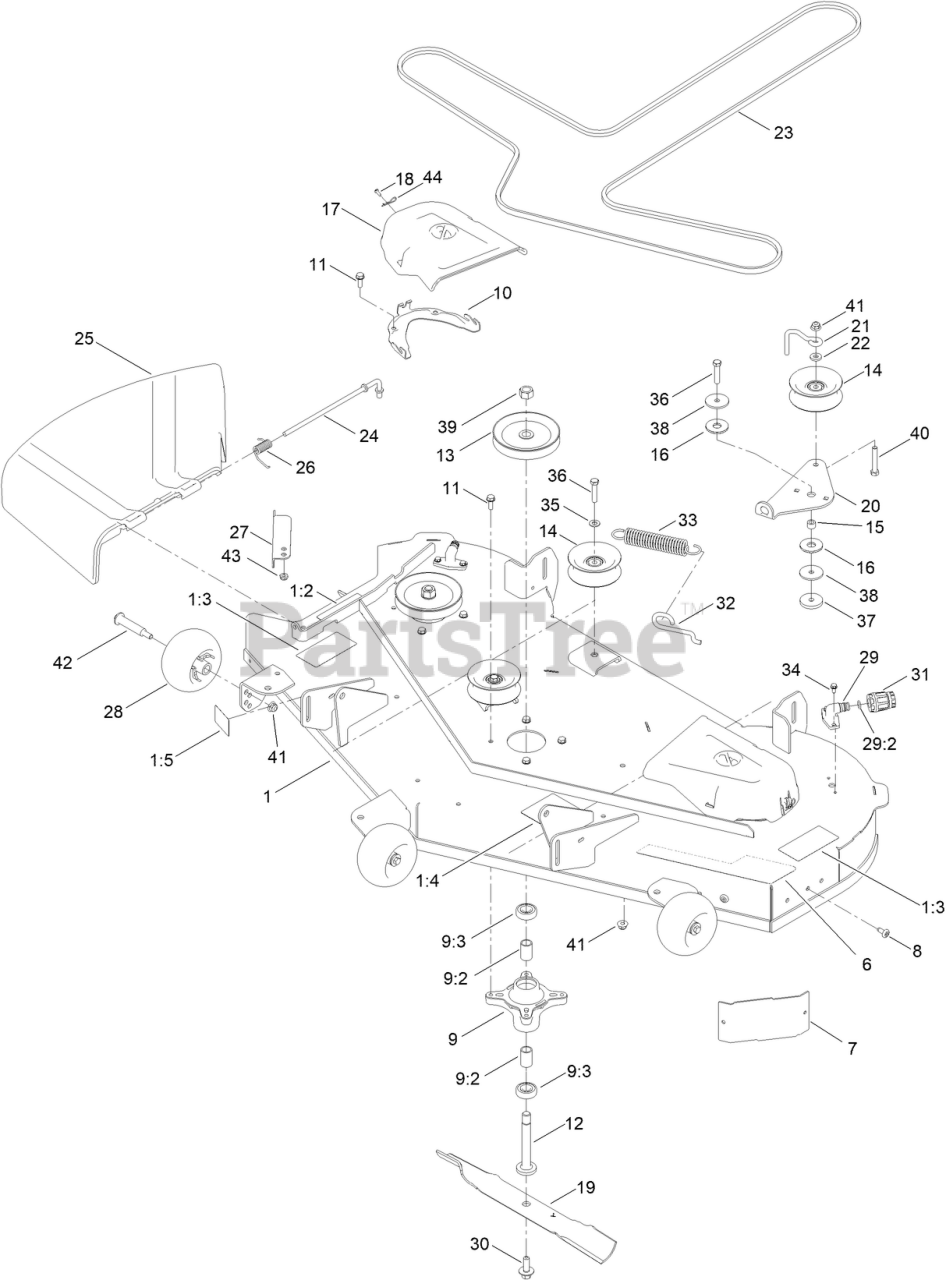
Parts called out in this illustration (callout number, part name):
1	54 IN DECK DECAL ASM
1:2	DECAL-DANGER
1:3	DECAL-DANGER, DECK
1:4	DECAL-ROUTING, BELT
1:5	DECAL-SCALP, ANTI
6	DECAL - IRON FORGED 54
7	BAFFLE-CORNER
9	SPINDLE ASM
9:2	SPACER
9:3	BEARING-BALL
10	BRACKET-COVER, BELT
11	SCREW-TAPTITE
12	SHAFT-SPINDLE
13	PULLEY ASM
14	PULLEY-IDLER, FLAT
15	SPACER
16	WASHER-FRICTION, COMPOSITE
17	COVER-BELT
18	SCREW
19	BLADE-HI LIFT
20	ARM-IDLER
21	BELT GUIDE - IDLER
22	SPACER-HUB, BLOWER
23	BELT-V (A SEC, 145.5 EL)
24	ROD-PIVOT
25	DEFLECTOR-DISCHARGE
26	SPRING-TORSION
27	BAFFLE-CUTOFF
28	ROLLER-SCALP, ANTI
29	FITTING-WASHOUT
29:2	O-RING
30	BOLT-BLADE, SEMS
31	CONNECTOR-HOSE
32	HOOK-RETURN SPRING
33	SPRING-EXTENSION
34	SCREW-HWH
35	WASHER-FLAT
36	SCREW-HH
37	WASHER-PLAIN
38	WASHER-REBOUND
39	NUT-HEX
40	SCREW-HH
41	NUT-HF, NI
42	BOLT-SHOULDER
44	PIN-HAIR
